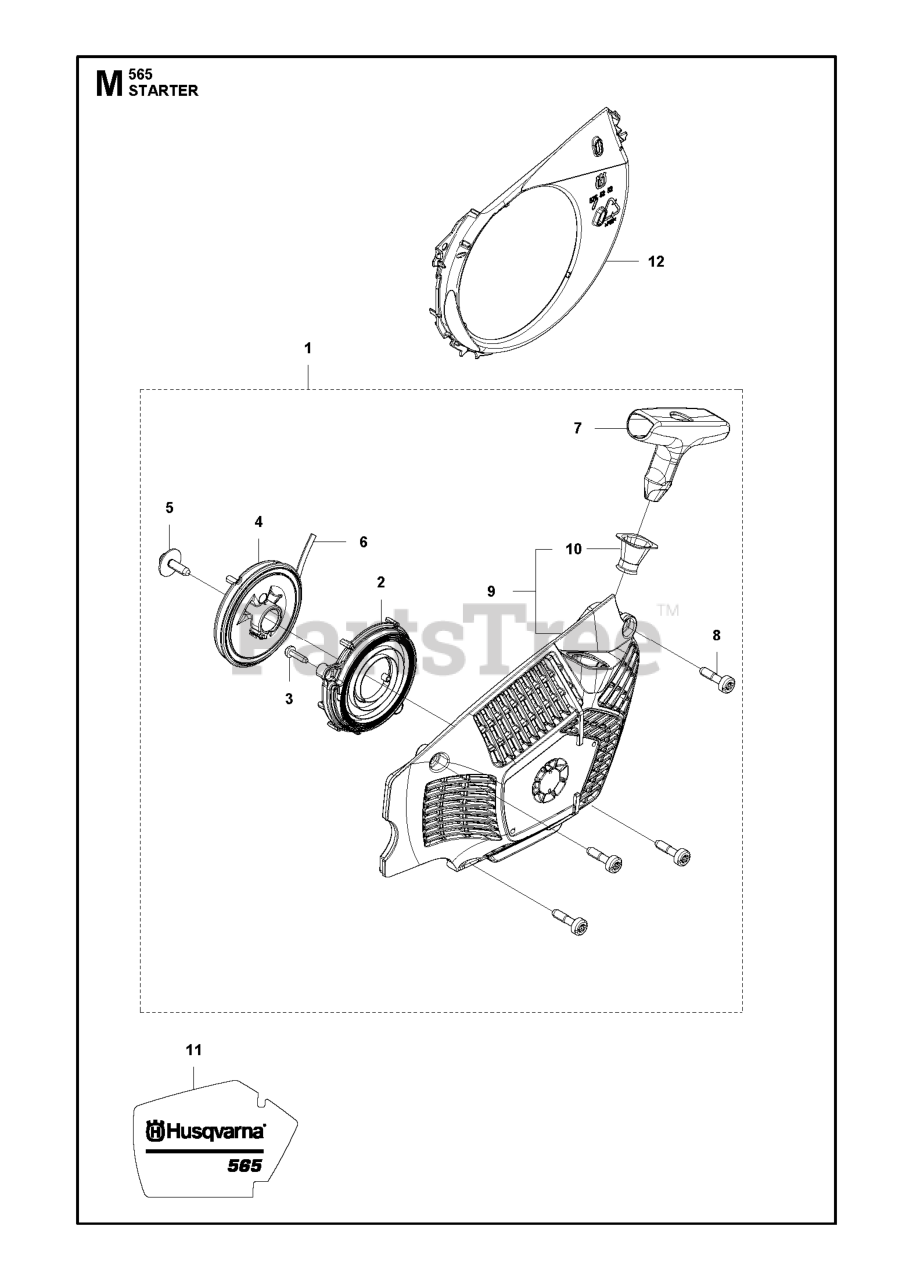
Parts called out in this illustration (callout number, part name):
1	STARTER HOUSING H565/H572 WITH
2	SPRING CASSETTE ADDY
3	SCREW CITXPANT
4	STARTER PULLEY ASSY
5	SCREW ITXSCT MT5X16 10.9 TBO
6	STARTER ROPE
8	SCREW CITXPANMO
9	STARTER HOUSING
12	BAFFLE AIR
